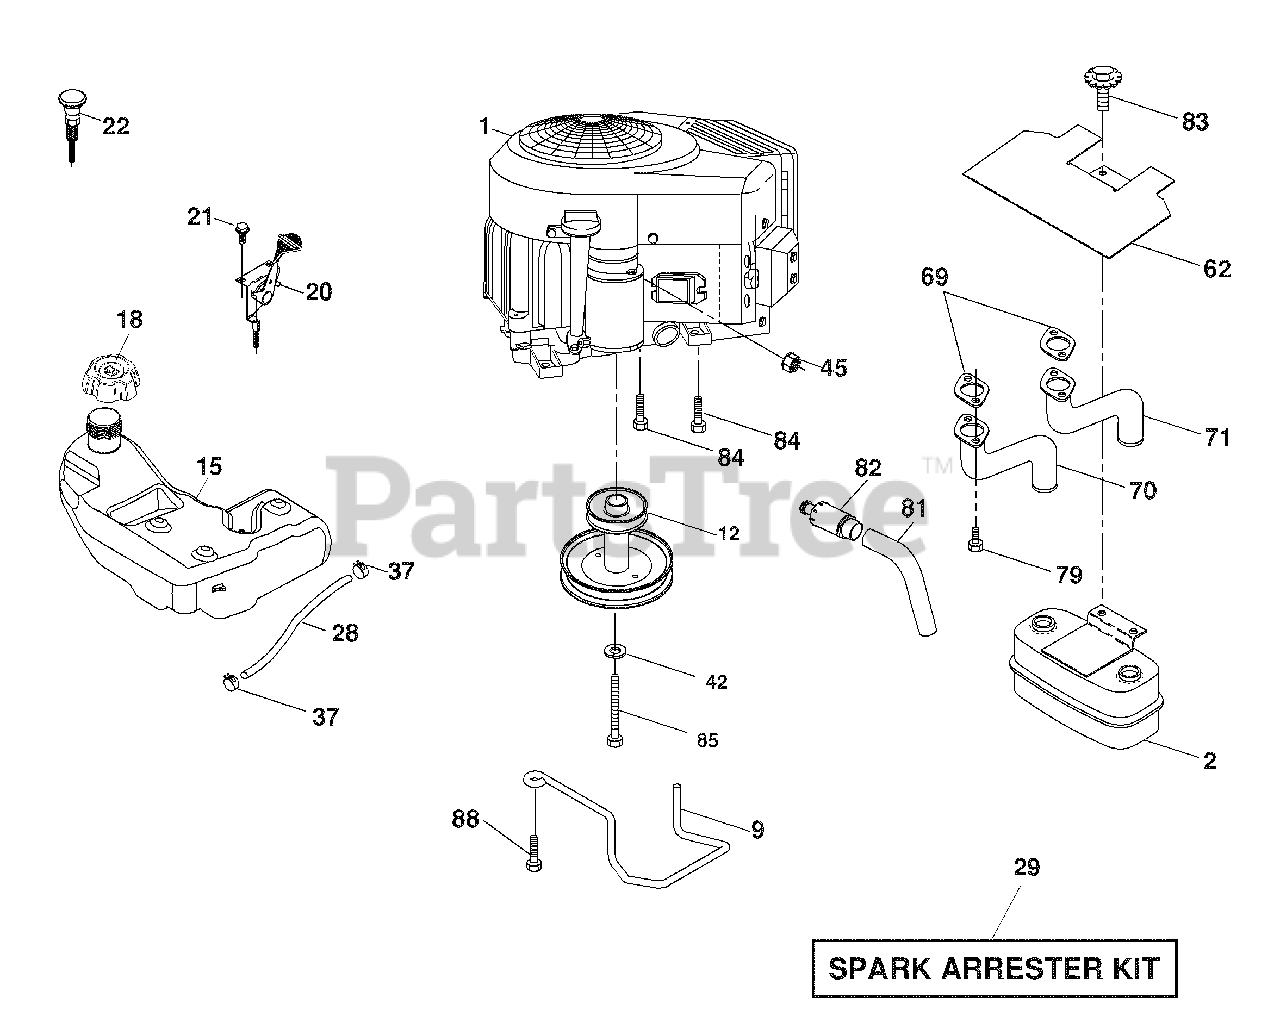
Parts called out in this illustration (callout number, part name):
9	Keeper Belt Engine
11	Clutch Ogura
12	Pulley Engine
15	Tank Fuel
18	Cap Asm
20	Control Throttle
21	Screw 10 x 3/4 Single Lead-Hex
22	Control Choke
28	Fuel Line
29	Spark Arrester Kit
31	Clip Push-In Hinged
37	Clamp Hose
41	Washer 1-1/2 OD x 15/32 ID x .250
42	Washer Lock 7/16
45	Nut Keps Hex 1/4-20 unc
62	Shield Heat Muffler
70	Exhaust Tube LH
71	Exhaust Tube RH
79	Screw Socket Head 5/16-18 x 1
81	Tube Drain Oil Easy
82	Plug Drain Oil
83	Bolt 5/16-18 unc x 3/4 w/Sems
84	Screw 3/8-16 x 1-1/4
85	Bolt Hex 7/16-20 x 4 x Gr. 5-1.5 Thr
90	Screw 3/8-16 x 1
